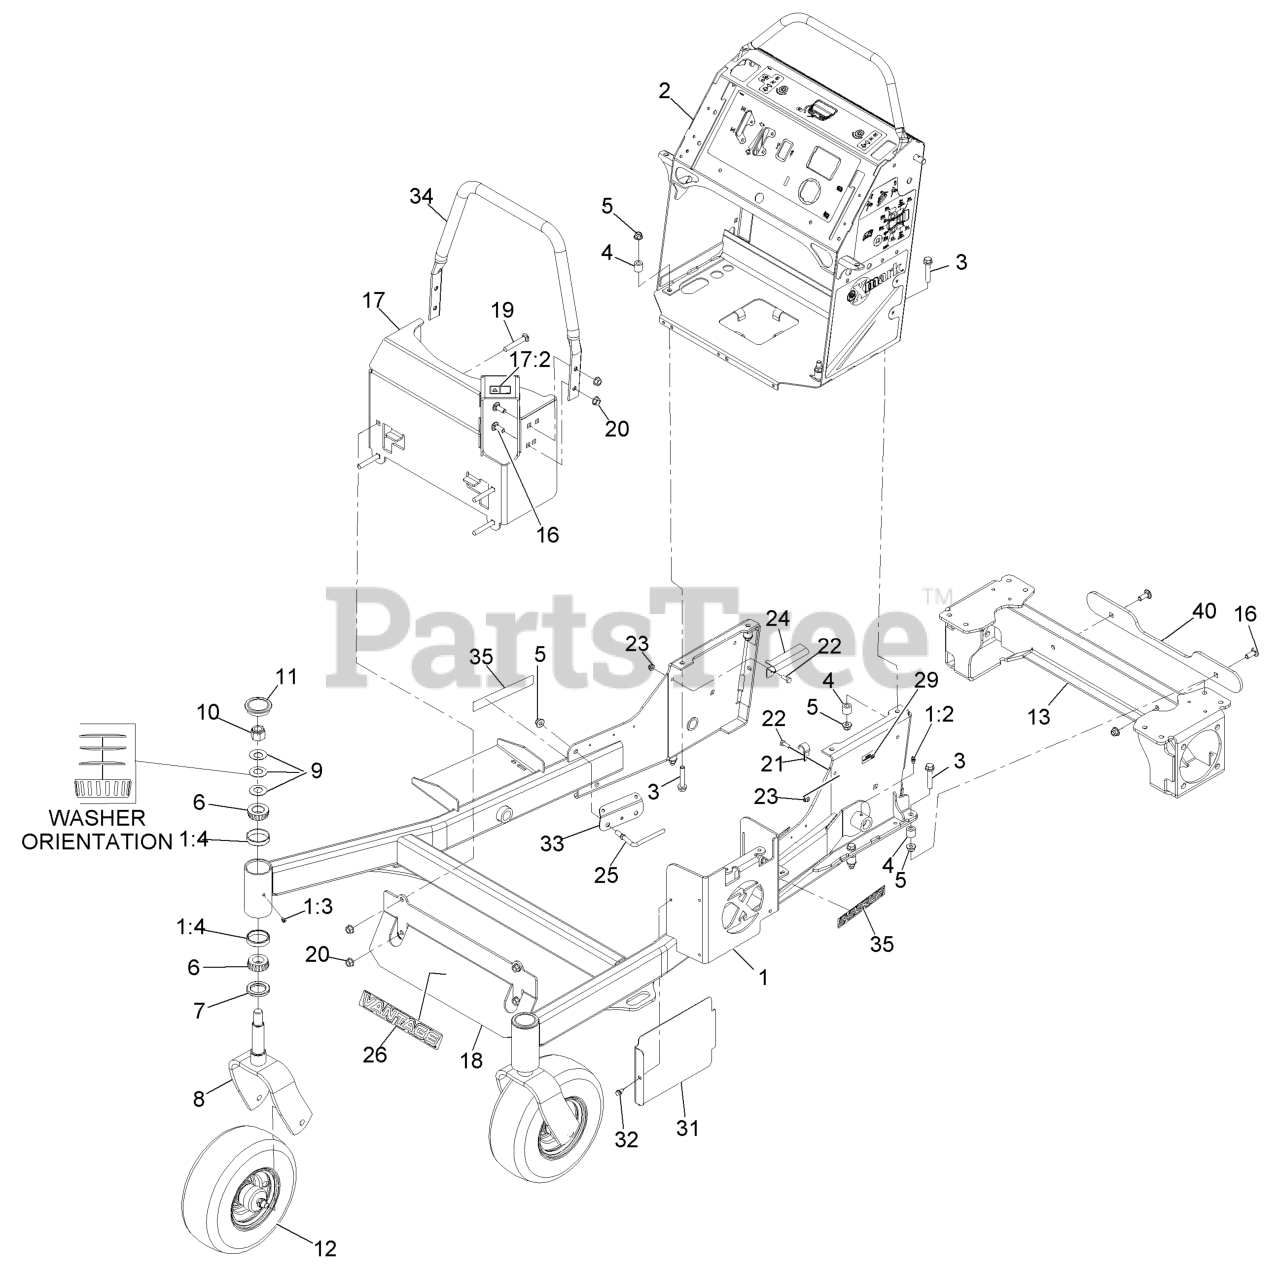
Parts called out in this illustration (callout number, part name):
1	FRONT FRAME ASM
1:2	FITTING-GREASE
1:4	CUP-BEARING
2	CONTROL TOWER ASM-EFI
3	SCREW-HHF
5	NUT-HF, NI
6	Cone-Bearing Tapered Roller
7	SEAL-GREASE
8	FORK-CASTER
9	WASHER-BELLVILLE
10	NUT-LOCK, NI
11	CAP-GREASE
12	WHEEL/TIRE AND BEARING AS
13	WELD, MOTOR FRAME
16	SCREW-CARR
17	ASM, MUFFLER GUARD W/ DEC
17:2	DECAL-WARNING
18	PANEL-GUARD
19	SCREW-CARR
21	CLAMP-CABLE
22	SCREW-HH
24	BRACKET-HOSE, FUEL
25	GUIDE-HOSE, SUPPORT
26	DECAL-VANTAGE LOGO
29	Decal-Patent Ttco.Com
31	SHIELD-HEAT, TALL
32	SCREW-HWH
33	GUARD-HOSE
34	TUBE-GUARD
35	DECAL-S-SERIES
40	PLATE, BUMPER SPACER
